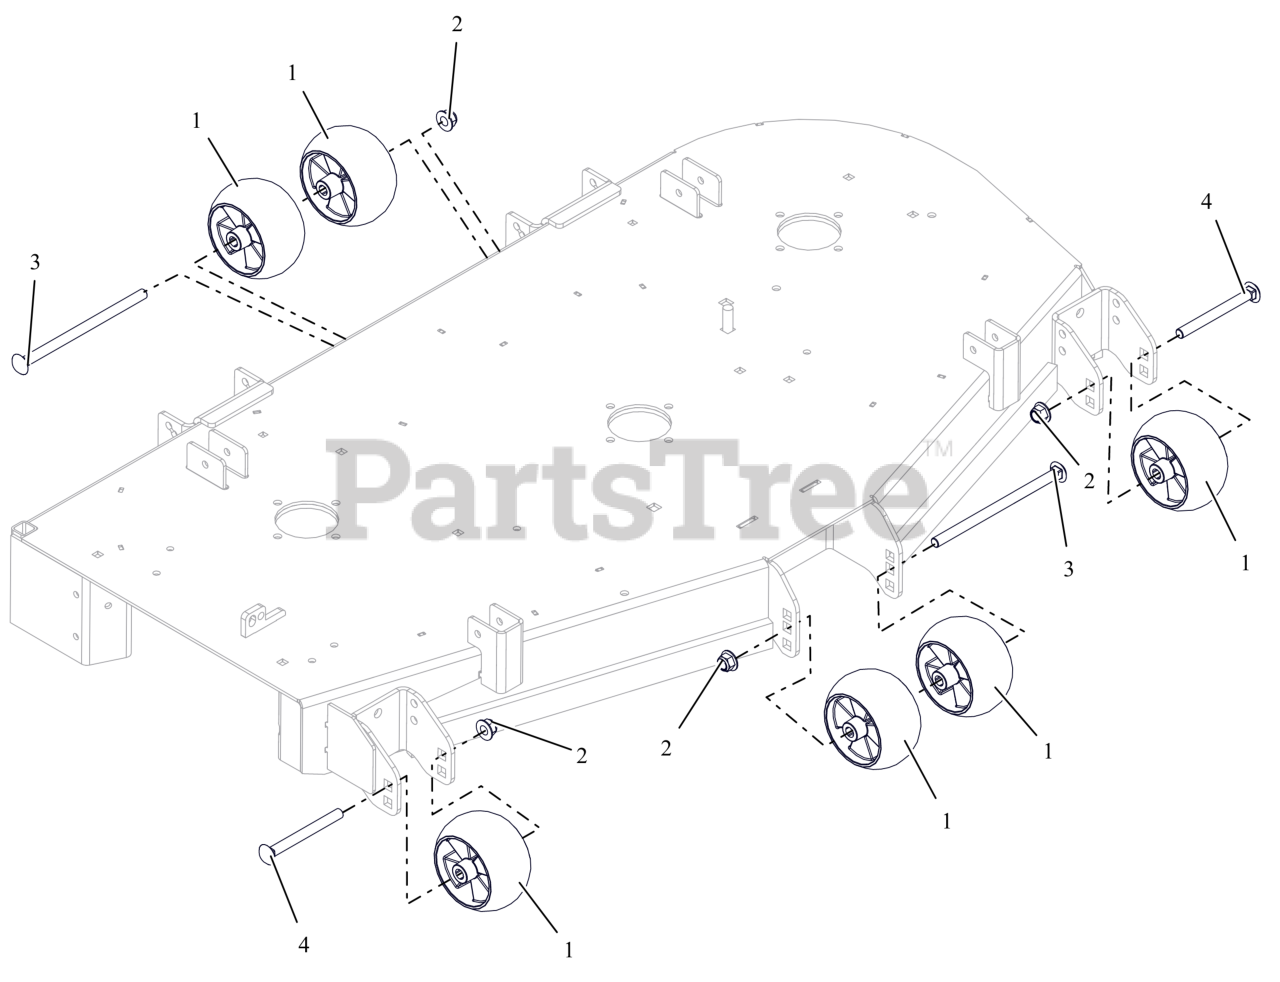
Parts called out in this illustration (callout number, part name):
1	WHEEL, ANTI SCALP - 5X3 CTR W/RIBS
2	NUT,NYL-FLG .50-13 GF ZCC
3	BTL,RHSN .500-13 X 8.5S G5 ZCC
4	BLT, RHSN .50-13X5.00 G5 ZCC
